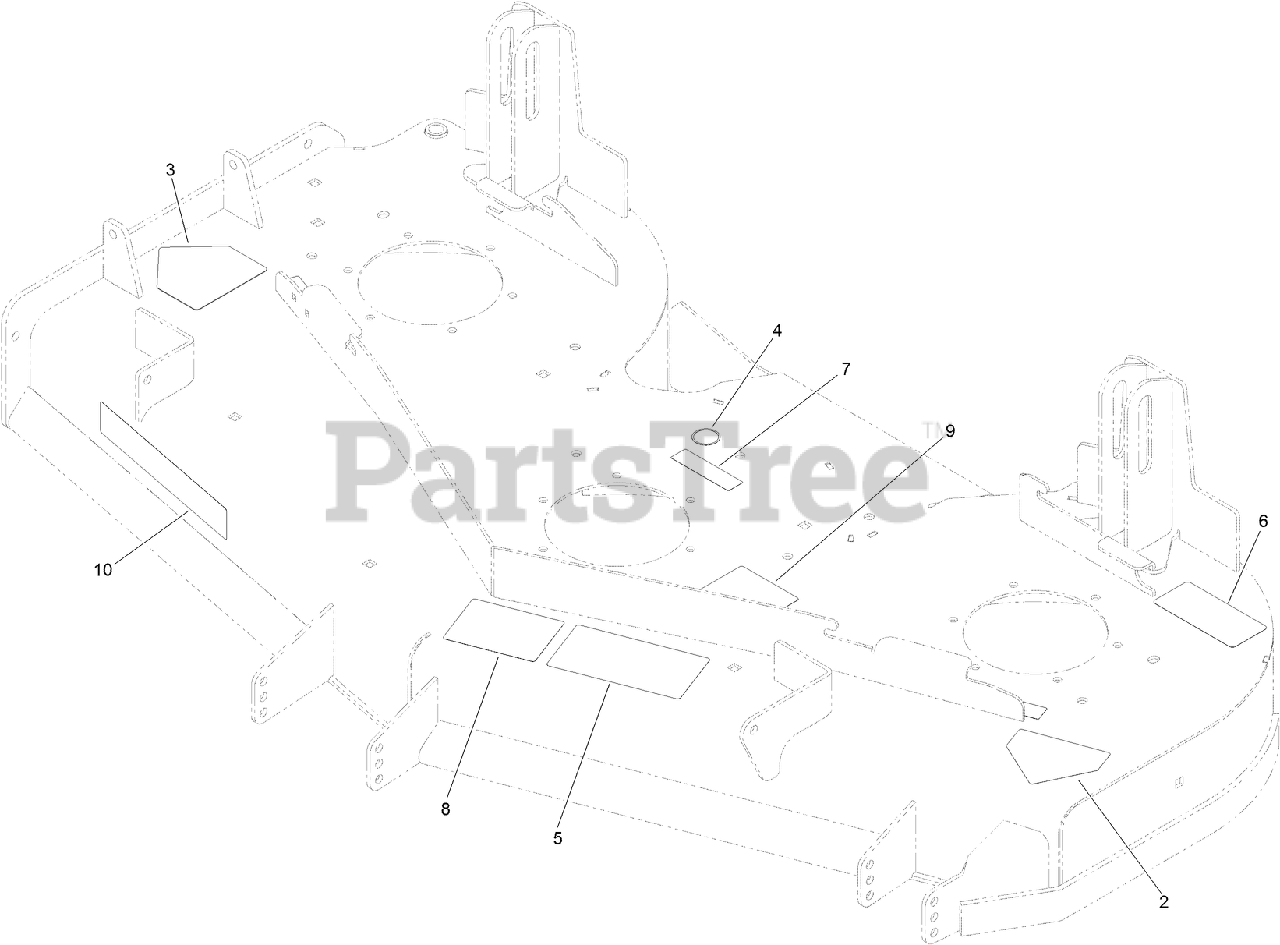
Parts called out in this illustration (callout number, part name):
2	DECAL-DANGER
3	DECAL-DANGER
4	DECAL-GREASE
5	DECAL-DANGER, THROWN OBJECT
6	DECAL-TORQUE
7	DECAL-COVER, MISSING
8	DECAL-SCALP, ANTI
9	DECAL-ROUTING, DECK BELT
